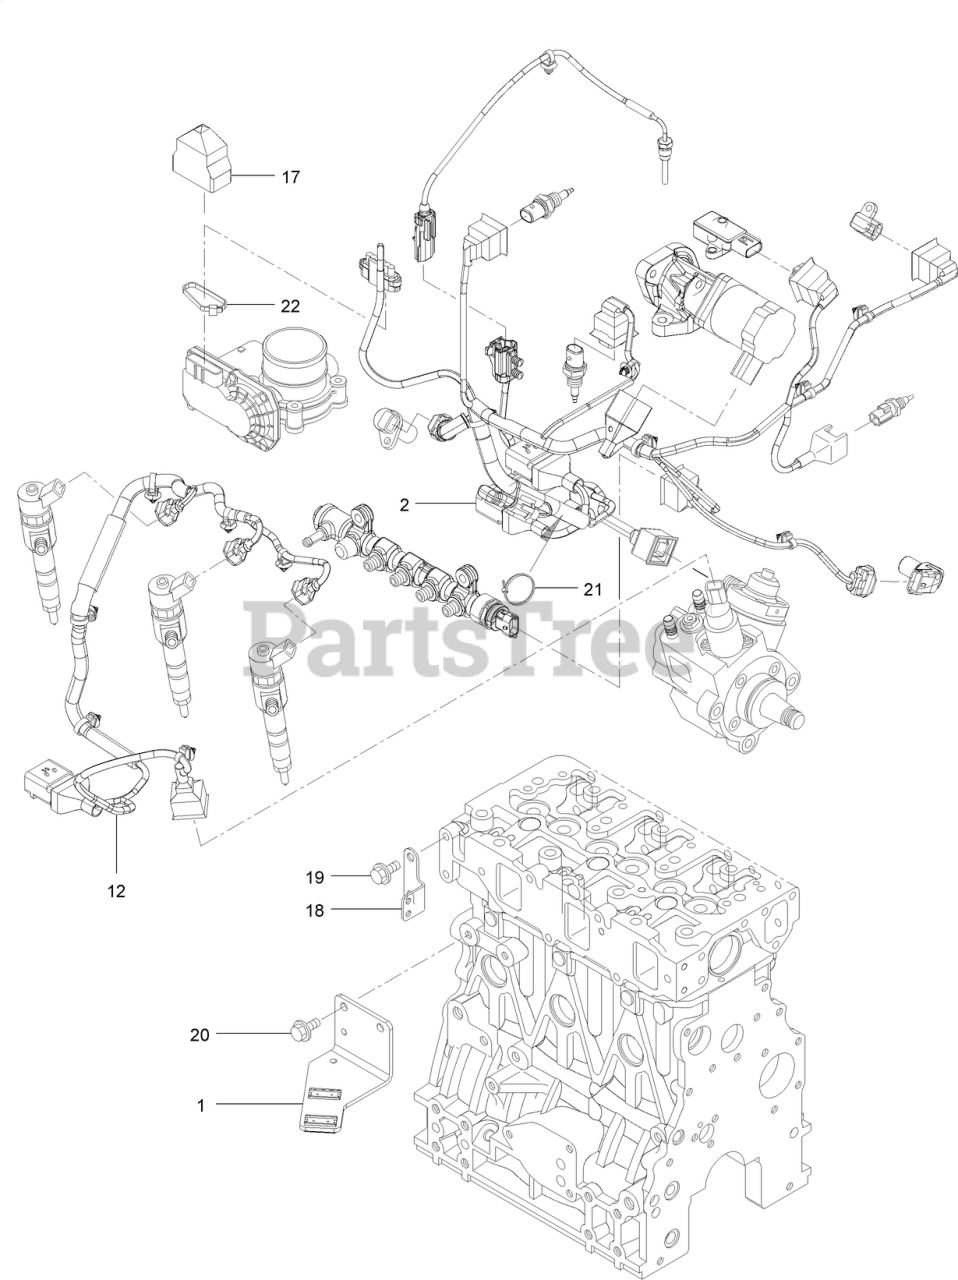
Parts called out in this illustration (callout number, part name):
1	BRACKET-CONNECTOR
2	HARNESS B-ENGINE, E C O
12	HARNESS
17	BOOT-CAP
18	BRACKET-HARNESS
